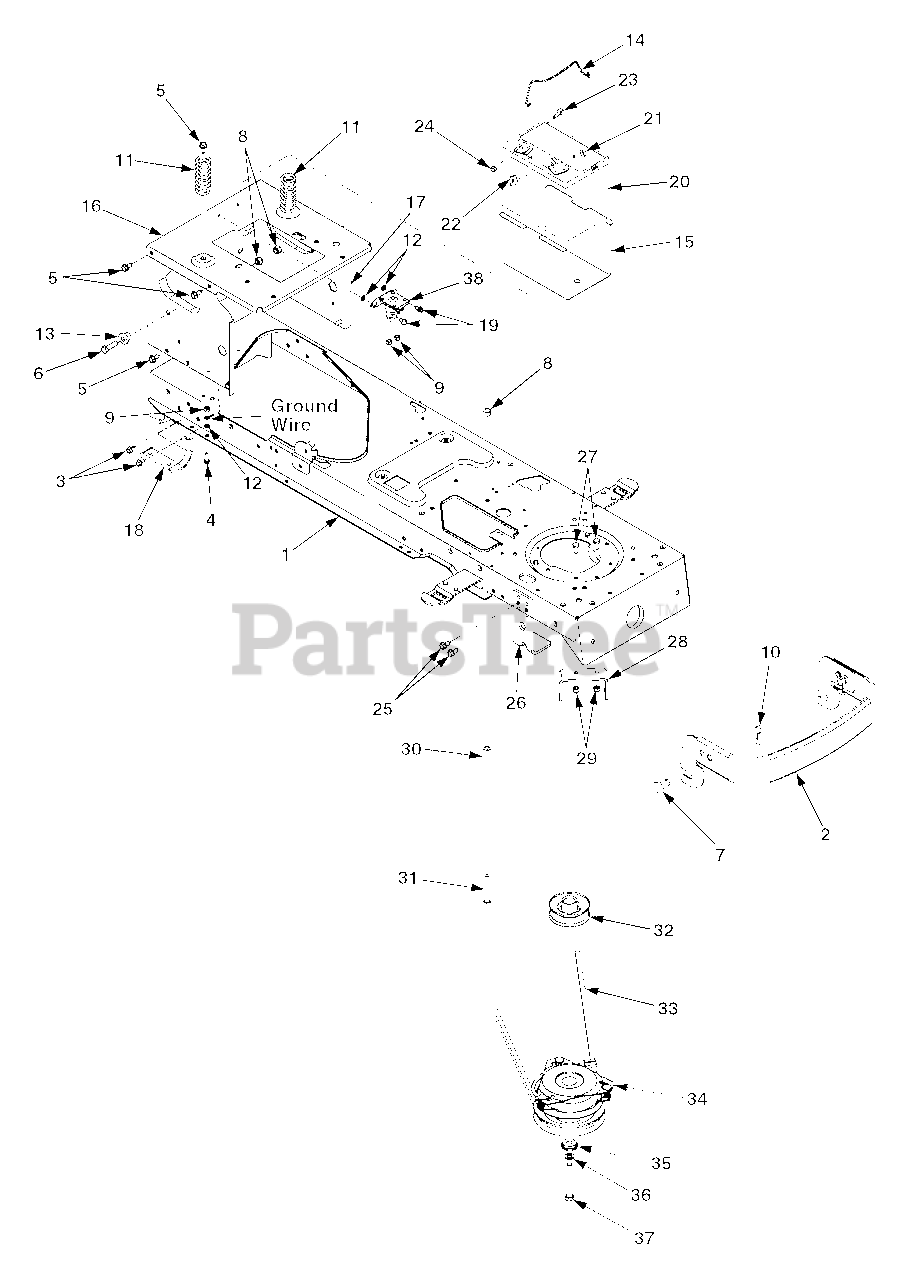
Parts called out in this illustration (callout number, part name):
4	TT Screw 1/4-20 x 0.75
5	Hex Wash. Hd. Tapp 5/16-12 x 75
6	Hex Bolt 3/8-16 x 1.25
7	Clevis Pin, .5 x .78
8	Nylon Lock Nut, 3/8-16 GR8
9	Lock Nut 1/4-20
10	Internal Cotter Pin
11	Compression Spring
12	Lock Washer
13	Shoulder Spacer
14	Battery Hold-Down Rod
19	TT Screw 1/4-20 x 0.5
20	Battery
21	Shoulder Screw, .25 x .15:1/4-20
22	Wing Nut, 1/4-20
23	Carriage Screw, 1/4-20 x .75
24	Hex Sems Nut, 1/4-20
25	Hex Wash. Hd. Tapp 5/16-12 x 75
27	Hex Bolt 5/16-18 x 0.625
31	Hex Bolt 3/8-16 x 2.5
32	Engine Pulley
33	V Belt
34	Electric Clutch
35	Shoulder Spacer
36	Lock Washer
37	Hex Bolt 7/16-20 x 3.75 GR5
38	Solenoid
